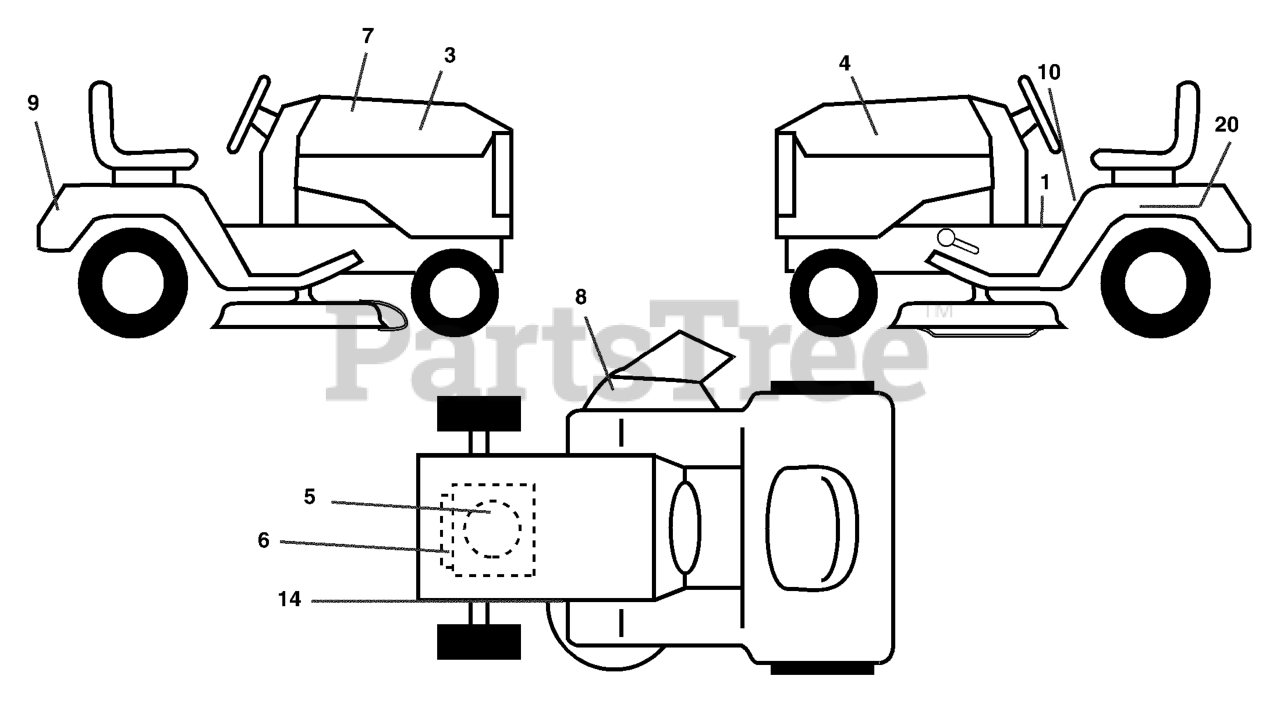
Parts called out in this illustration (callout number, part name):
1	DECAL FEND STLT OPER INST E/F
3	DECAL HOOD RH
4	DECAL HOOD LH
5	DECAL HOOD CUST. RESP.
6	DECAL ENGINE
7	DECAL REPLACEMENT
8	DECAL.WARN.KEEP.HAND.AWAY
9	DECAL, FENDER
10	DECAL FENDER DANGER
14	DECAL V-BELT SCHEMATIC
20	DECAL BTRY SYMBOLS
